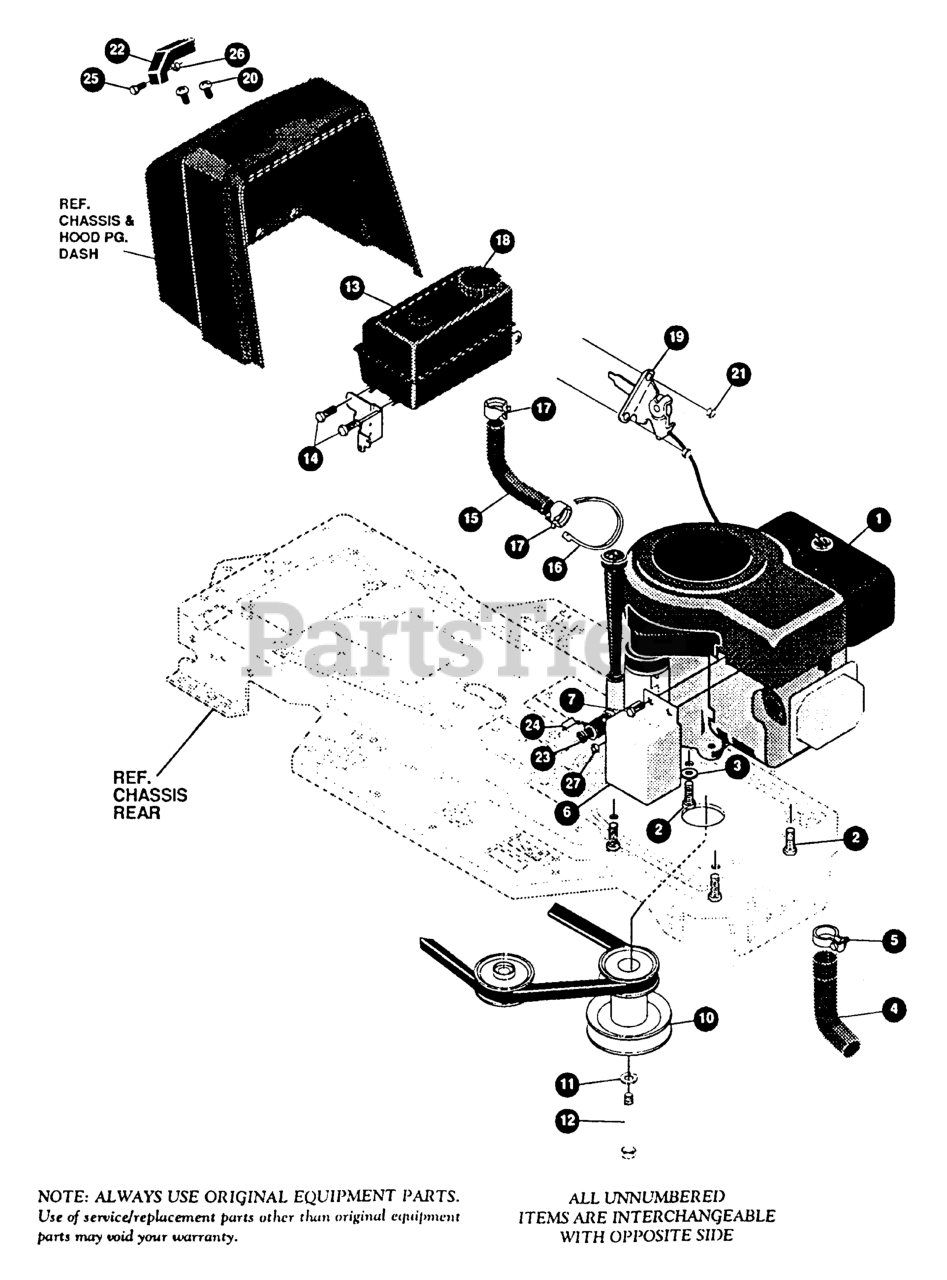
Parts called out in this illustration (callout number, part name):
2	SCREW, 3/8-16 X 1.25
3	WASHER, .384 X .69 X .04
4	EXHAUST TUBE
5	CLAMP, EXHAUST
6	HEAT SHIELD
7	SCREW, 1/4-20 X .50
10	PULLEY, ENGINE
11	WASHER, .459 X .78 X .11
12	SCREW, 7/16-20 X 5.00
13	TANK, FUEL
14	SCREW, 1/4-10 X .75
15	TUBING, .25 X .50 X BULK GAS LINE
16	TIE, CABLE
17	CLAMP, FUEL
18	CAP, FUEL
19	THROTTLE, CONTROL
20	SCREW, 10-24 X .63
21	NUT, #10-24
22	KNOB, THROTTLE CONTROL
23	OIL DRAIN VALVE ASSEMBLY
24	CAP, OIL
25	SCREW, 1/8-32 X .38
26	NUT, #8-32
27	NUT, 1/4-20
